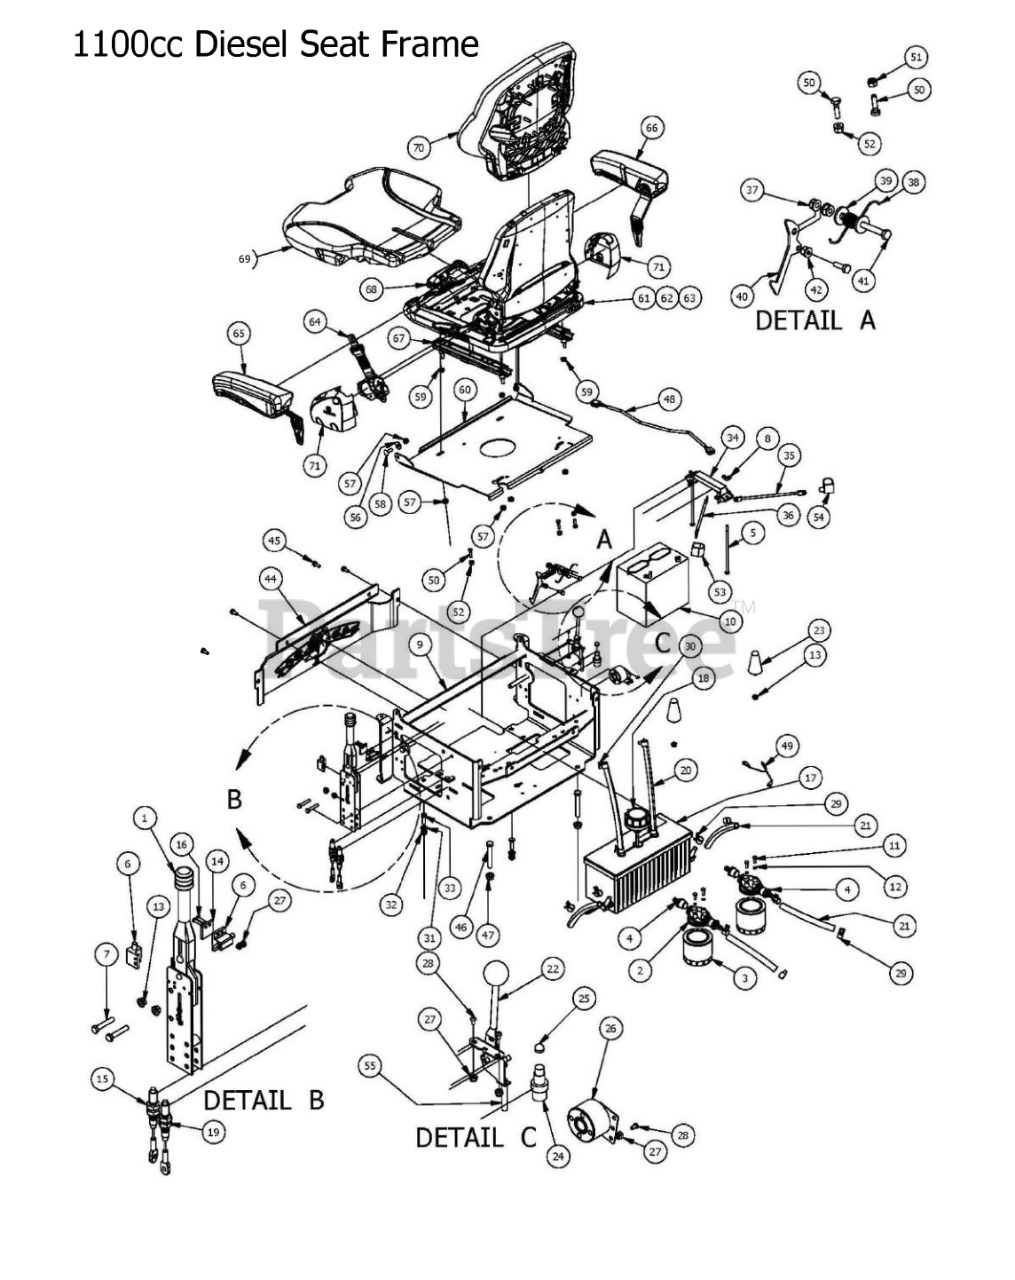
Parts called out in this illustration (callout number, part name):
1	Hand Brake Assembly
2	Filter Head
3	Hydraulic filter
4	Filter Head Fitting
5	1/4-20 X 9 Carriage Bolt
7	5/16" x 1 3/4" Hex Bolt
8	1/4" Wing Nut
9	2007 Diesel Seat Frame
10	Battery - Diesel Models - 151
11	1/4" x 3/4" Hex Bolt
12	1/4" Lock Washer
13	5/16" Flange Nut w/Serrations
14	Switch Block Plastic
15	Short Brake Cable
16	1024 x 1" Allenhead Bolt
17	Aluminum Hydraulic Tank
18	Hydraulic Tank Cap
19	Long Brake Cable
20	3/8" x 32" Clear Hose
21	1/2" x 9 1/4" Braided Hose
22	Throttle - Diesel
23	Spring Cushion
24	Momentary Start Switch
25	Start Switch Boot - Diesel
26	Heat Waming Piezo Buzzer
27	#10 Nylock Nut
28	1024 X 5/8" Buttonhead Bolt
29	1/2 Hose Clamp
30	3/8 hose clamp
31	3/8" Flat Washer
32	3/8" Flange Nut
33	3/8" x 1 1/4" Hex Bolt
34	Battery Hold Down
35	Black Battery Cable - Diesel
36	Red Battery Cable - Diesel
37	5/16-18 Nylon Flange Nut
38	Torsion Spring for Seat latch
39	.360 ID Plastic Washer
40	Seat Latch Lever
41	5/16-18 X 2 Hex C/S (GR.5) ZC
42	1/4-20 Nylon Insert flange Nut
43	1/4-20 x 1-1/4 GR 5 Hex Bolt
44	Cooler Cover
45	5/16 x 3/4 washer head type F screw
46	1/2 x 3 1/2 Flange Bolt Grade 8
47	1/2" Flange Nut
48	Seat Switch Adapter
49	Seat Cable
50	1/4-20 x 1 GR 5 hex bolt zinc
51	1/4 Nylock Nut
52	1/4-20 Nylon Insert flange Nut
54	Black Boot For Ground Cable
55	Diesel Throttle Cable Only
56	.360 ID Plastic Washer
57	5/16-18 Nylon Flange Nut
58	5/16" x 1" Carriage Bolt
59	5/16" Flange Nut
60	Seat Plate
61	Grammer Seat With Seatbelt
62	Grammer Seat Without Seatbelt
63	Grammer Seat Black and Orange
64	Grammer Seat Belt Kit
65	Left Armrest Kit for Grammer Seat
66	Right Armrest Kit for Grammer Seat
67	Rails for Grammer Seat (Pair)
68	Grey Handle Assembly for Grammer Seat
69	Seat Cushion for Grammer Seat
70	Back Cushion for Grammer Seat
71	Plastic Side Covers for Grammer Seat
